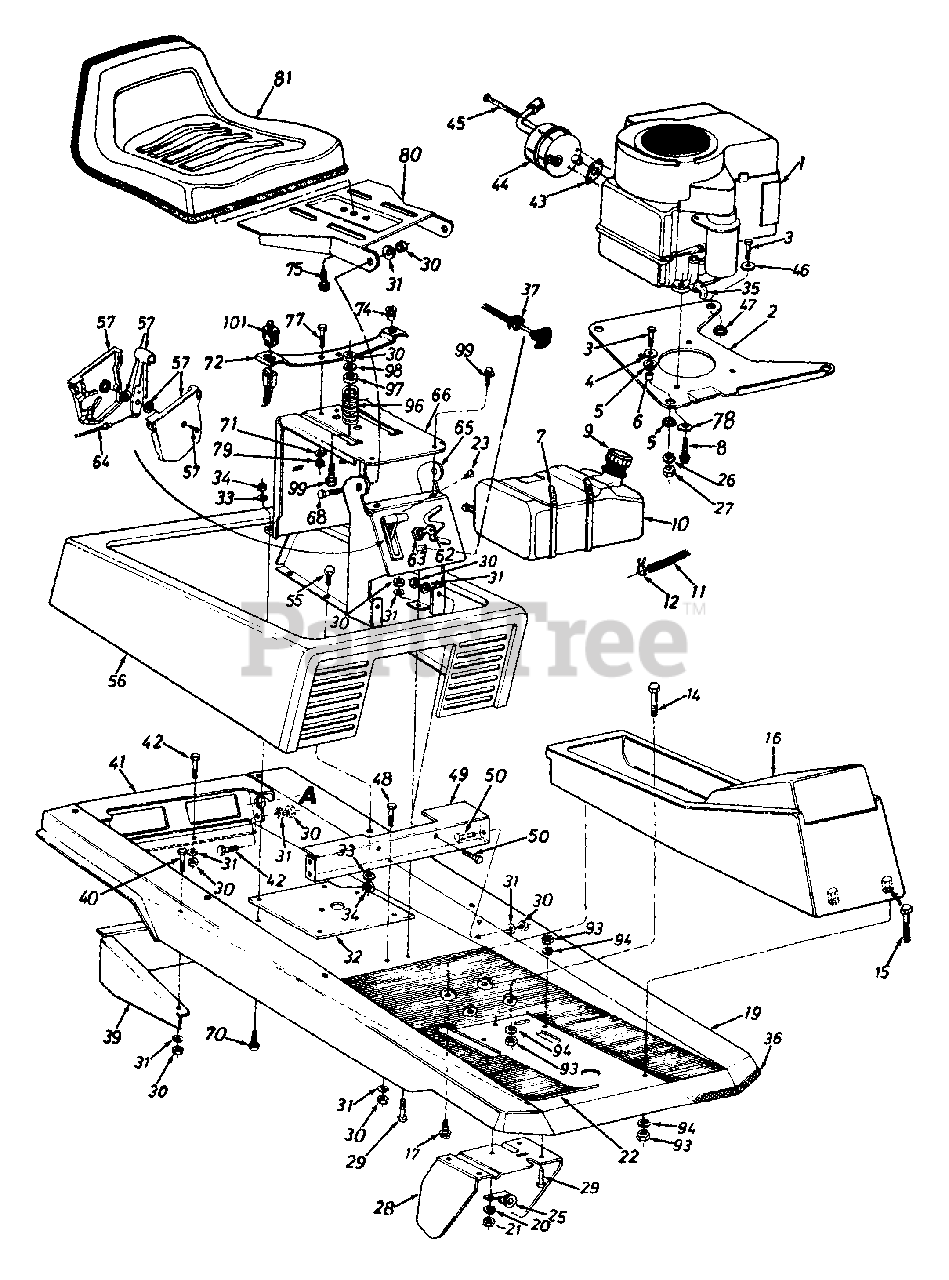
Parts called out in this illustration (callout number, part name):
1	Engine
4	Fl-Wash. .330" I.D. x 1.125" O.D.
5	Engine Mounting Grommet
6	Spacer .315" I.D. x .50" O.D. x .520" Lg.
7	Cable Tie 30.6" Lg.
8	Hex Wash. Hd. Self-Tap Scr. 3/8-16 x 1.25" Lg.
9	Gas Cap
10	Fuel Tank
11	Gas Line - 26 Inches
12	Hose Clamp - 1/2" O.D. Tube
14	Hex Bolt 5/16-18 x 1.75" Lg.
15	Hex Bolt 5/16-18 x 2.0" Lg.
16	Front Console
17	Plastite Scr. 5/16 x 1.25" Lg.
19	Main Frame
20	L-Wash. 5/16" I.D.
21	Hex Nut 5/16-18 Thd.
23	Truss Mach. AB-Tap Scr. #10 x .50" Lg.
26	L-Wash. 5/16" I.D.
27	Hex Nut 5/16-24 Thd.
28	Clutch-Brake Pedal Ass'y.
29	Hex Bolt 5/16-18 x .75" Lg
30	Hex Nut 5/16-18 Thd.
31	L-Wash. 5/16" I.D.
34	Hex Nut 1/4-20 Thd.
35	90ø Elbow Male To Female
36	Trim Strip 57" Lg.
37	Choke Control
43	Exhaust Gasket
44	Muffler Ass'y.
45	Shld. Bolt
46	Fl-Wash. .33" I.D. x 1.25" O.D.
47	Flange Wash. .32" I.D. x .75" O.D.
48	Hex Bolt 5/16-18 x .75" Lg.
49	Seat Support & Frame Brkt.
50	Hex Bolt 5/16-18 x .75" Lg.
55	Hex Bolt 1/4-20 x .50" Lg.
62	Ignition Key
63	Ignition Switch
64	Throttle Control Wire 35" Lg.
70	Hex Tap Scr. 1/4-20 x 1.0" Lg.
71	L-Wash. 5/16" I.D.
75	Hex Wash. Hd. Tap Scr. 3/8-16 x 3/4" Lg.
77	Hex Bolt 5/16-18 x .75" Lg.
78	Bell-Wash. .345" I.D. x .88" O.D.
79	Hex Cent. L-Nut 5/16-18 Thd.
80	Seat Pivot Bracket
81	Seat Ass'y.
93	Hex Nut 5/16-18 Thd.
94	L-Wash. 5/16" I.D.
96	Compression Spring 2.61" Lg.
98	Fl-Wash. .344" I.D. x .875"
99	Hex Bolt 5/16-18 x 1" Lg. (Gr. 5)
